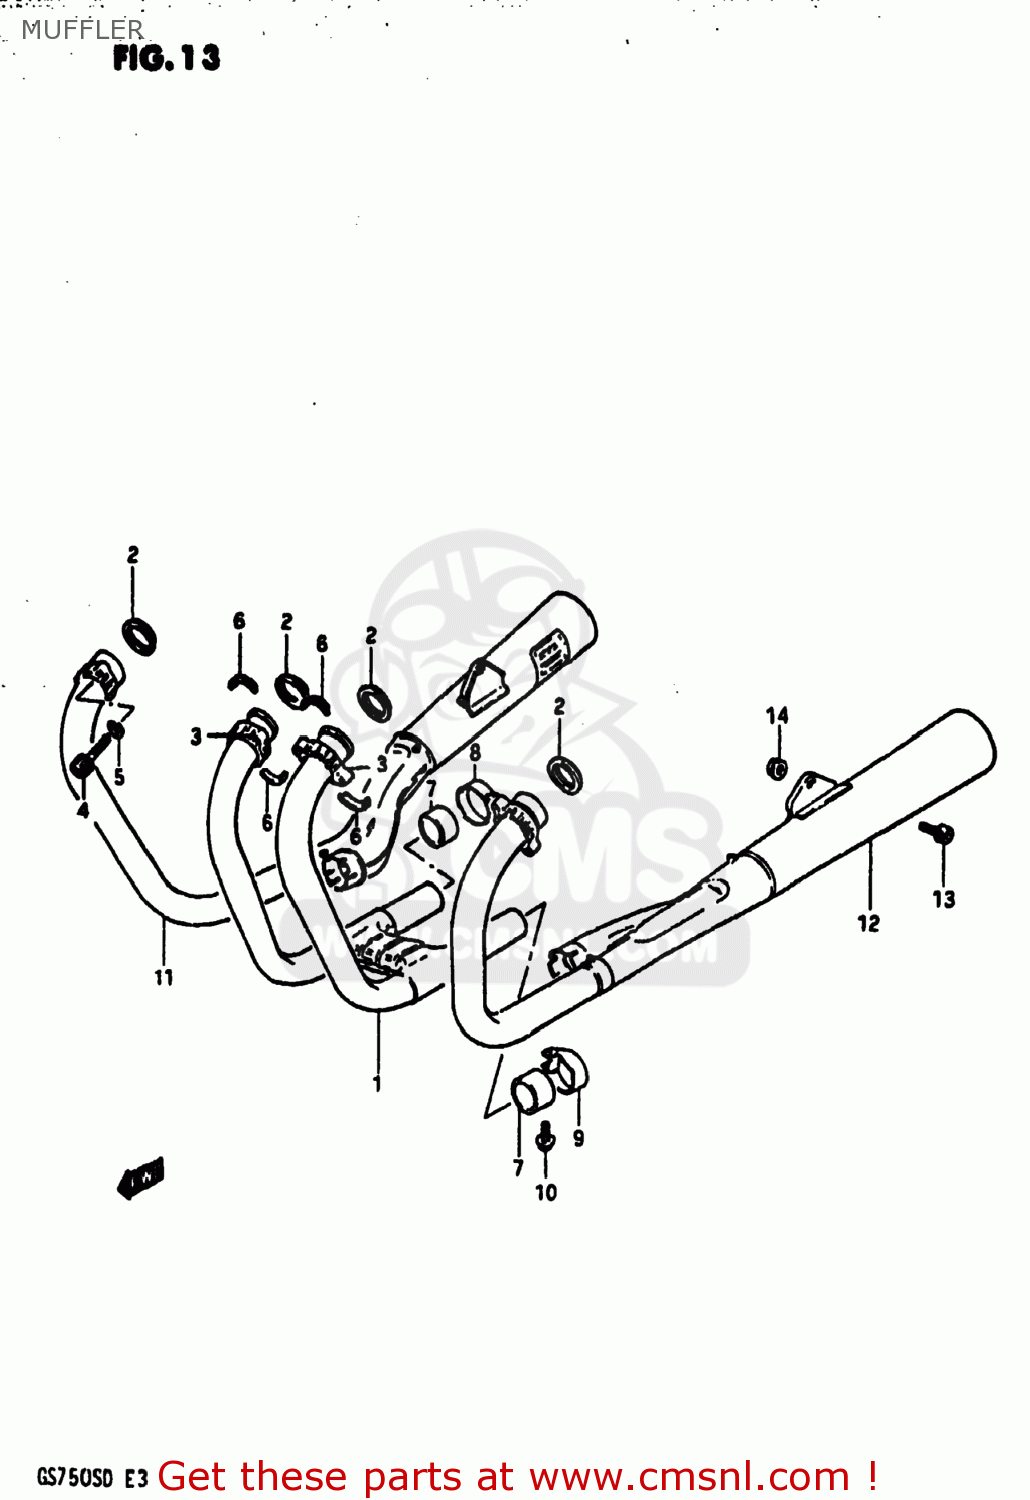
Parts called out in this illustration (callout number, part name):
1	PIPE,EXHAUST
2	GASKET,EXHAUST PIPE (NAS)
3	CLAMP(H:21)
4	BOLT
5	LOCK WASHER
6	PLATE,EXHAUST
7	CONNECTOR,MUFFLER
8	CLAMP,MUFFLER CONNECTOR,R
9	CLAMP,MUFFLER CONNECTOR,L
10	BOLT
11	MUFFLER ASSEMBLY
12	MUFFLER ASSEMBLY
13	BOLT
14	NUT
